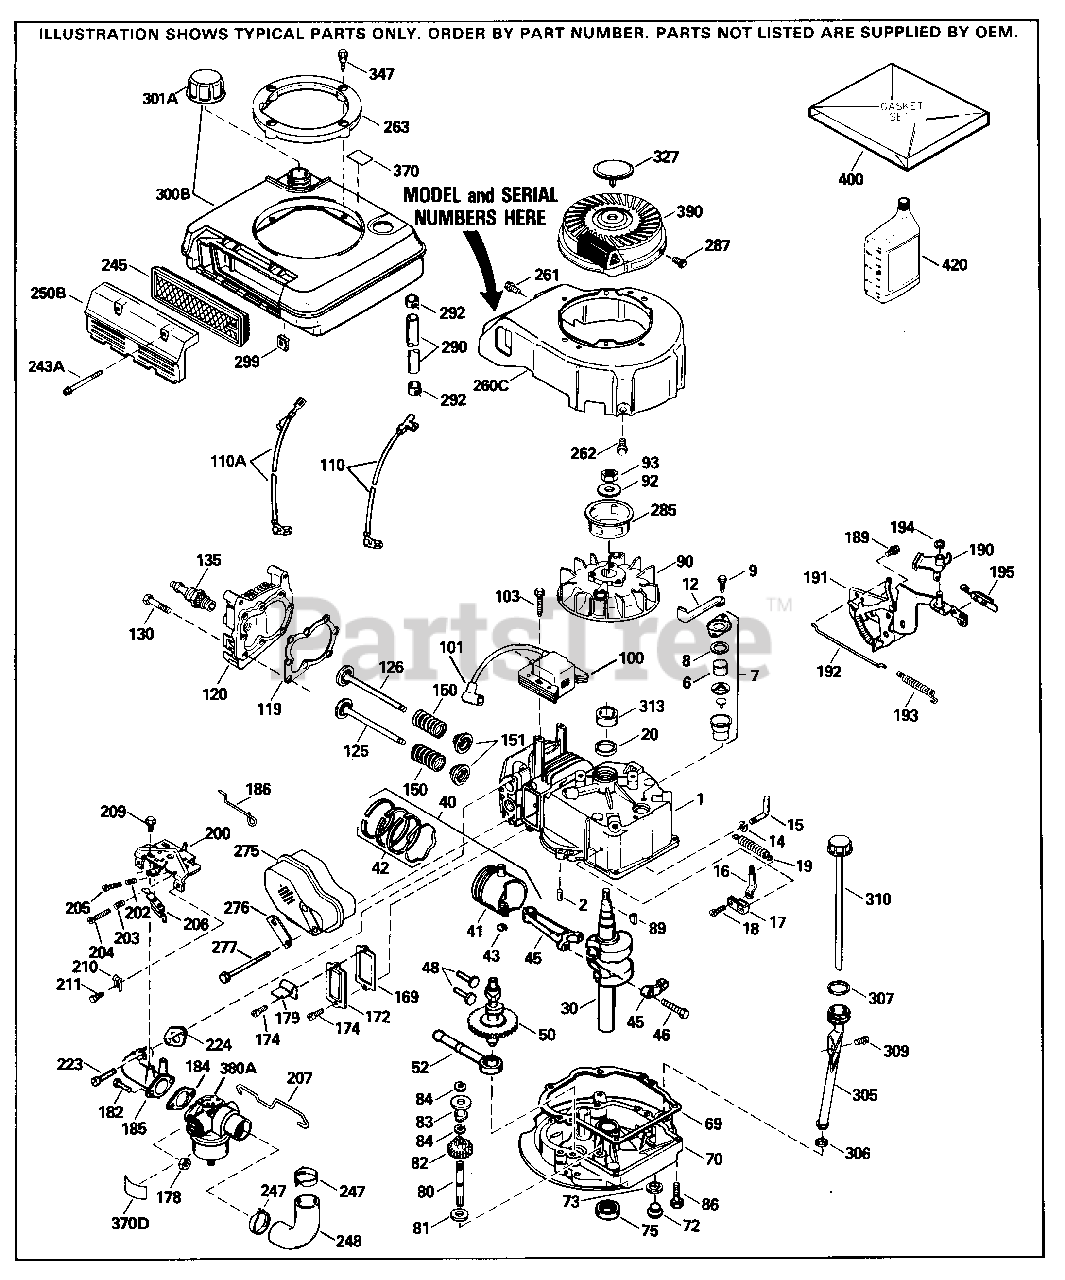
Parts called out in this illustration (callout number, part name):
1	"Cylinder (Incl. 2,7,20 & 125)
2	Dowel Pin
6	Breather Element
7	Breather Body Ass'y. (Incl. 6 & 12)
12	Breather Cover & Tube
14	Flat Washer
15	Governor Rod (Incl. 14)
16	Governor Lever
17	Governor Lever Clamp
18	Screw, 8-32 x 5/16"
19	Extension Spring
20	Oil Seal
30	Crankshaft
40	Piston, Pin & Ring Set (Std.)
40	Piston, Pin & Ring Set (.010" OS)
40	Piston, Pin & Ring Set (.020" OS)
41	Piston & Pin Ass'y. (Std.) (Incl. 43)
41	Piston & Pin Ass'y. (.010" OS) Incl. 43
41	Piston & Pin Ass'y. (.020" OS) Incl. 43
42	Ring Set (Std.)
42	Ring Set (.010" OS)
42	Ring Set (.020" OS)
43	Piston Pin Retaining Ring
45	Connecting Rod Ass'y. (Incl. 46)
46	Connecting Rod Bolt
48	Valve Lifter
50	Camshaft (BCR)
52	Oil Pump Ass'y.
69	* Mounting Flange Gasket
70	Mounting Flange (Incl. 72 thru 83)
72	Oil Drain Plug
72A	Oil Drain Plug
75	Oil Seal
80	Governor Shaft
82	Governor Gear Ass'y.(Incl. 81)
83	Governor Spool
86	Screw, 1/4-20 x 1-1/4"
89	Flywheel Key (also available in Packa ged Part #740007B)
90	Flywheel
92	Belleville Washer
93	Flywheel Nut
100	Solid State Ignition
101	Spark Plug Cover
103	Screw, Torx T-15, 10-24 x 15/16"
110	Ground Wire
119	* Cylinder Head Gasket
120	Cylinder Head
125	Exhaust Valve (Std.) (Incl. 151)
125	Exhaust Valve (1/32" OS) (Incl. 151)
126	Intake Valve (Std.) (Incl. 151)
126	Exhaust Valve (1/32" OS) (Incl. 151)
130	Screw, 5/16-18 x 1-1/2"
135	Resistor Spark Plug (RJ19LM) also ava ilable in Packaged Part #740081
150	Valve Spring
151	Valve Spring Cap
169	* Valve Cover Gasket
172	Valve Cover
174	Screw, 10-24 x 9/16"
178	Nut & Lock Washer 1/4-28
179	Retainer Clip
182	Screw, 1/4-28 x 7/8"
184	* Carburetor To Intake Pipe Gasket
185	Intake Pipe (Incl. 224)
186	Governor Link
200	Control Bracket (Incl. 202 thru 206)
202	Compression Spring
203	Compression Spring
204	Screw, 5-40 x 7/16"
205	Screw, 6-32 x 21/32"
206	Terminal
207	Throttle Link
209	Screw, 10-24 x 9/16"
215	Control Knob
223	Screw, 1/4-20 x 1"
224	* Intake Pipe Gasket
238	Screw, 10-32 x 5/8"
245	Air Filter (Poly) (also available in Packaged Part #740023B)
261	Screw, 10-24 x 9/16"
262	Screw, 1/4-20 x 1/2"
275	Muffler (Incl. 277)
277	Screw, 1/4-20 x 2-5/16"
285	Starter Cup
287	Screw, 8-32 x 21/64"
290	Fuel Line
292	Fuel Line Clamp
298	Screw, 10-32 x 35/64"
305	Oil Fill Tube
306	* "O"-Ring
307	"O" Ring
309	Screw, 10-32 x 1/2"
310	Dipstick
327	Starter Plug
370A	Lubrication Decal
370B	Control Decal
390	Rewind Starter NOTE: This engine cou ld have been built with 590688 starte r. Refer to the design of the air int ake louvers for part identification. Individual starter parts do not inter change.
400	* Gasket Set (Incl. items marked PK in notes) Incl. part #'s: 26756 (1), 272 34A (1), 33735 (1), 34265 (1), 34338 (1), 34690A (1), 35261 (1), 36477 (1)
416	Spark Arrestor Kit (Incl. 417) Option al
417	Screw, 8-32 x 3/8" (Optional)
420	SAE 30 4-Cycle Engine Oil (Quart)
